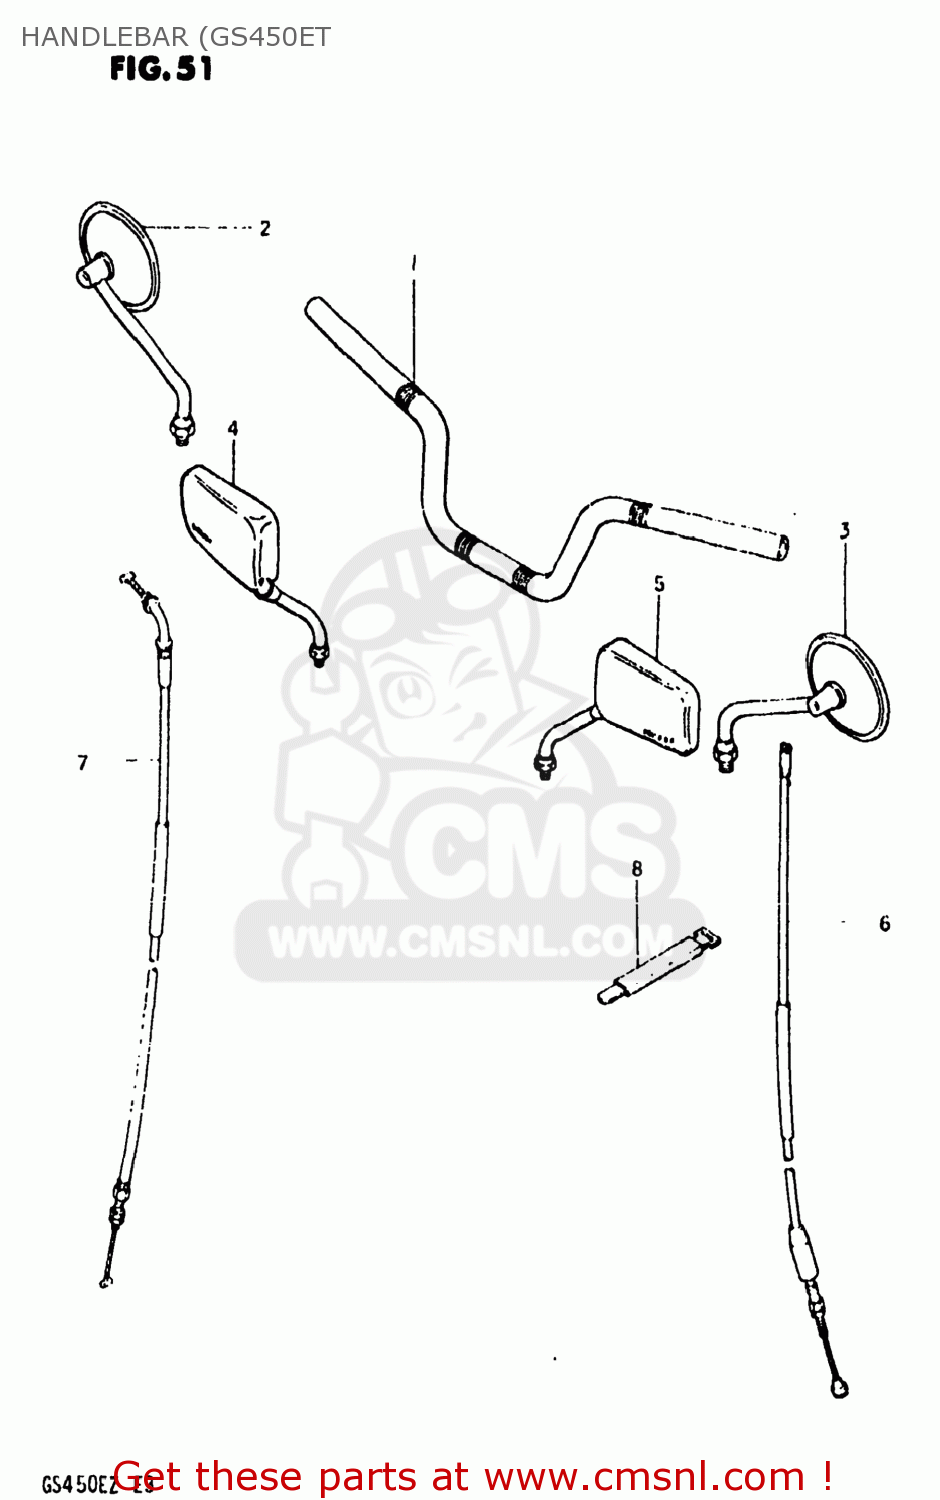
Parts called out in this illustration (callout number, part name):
1	HANDLEBAR
2	MIRROR ASSEMBLY,RIGHT
3	MIRROR ASSEMBLY,LEFT
4	MIRROR ASSEMBLY,REAR VIEW
5	MIRROR ASSEMBLY,REAR VIEW
6	CABLE ASSY,CLUTCH
7	CABLE ASSEMBLY,THROTTLE
8	CLAMP
